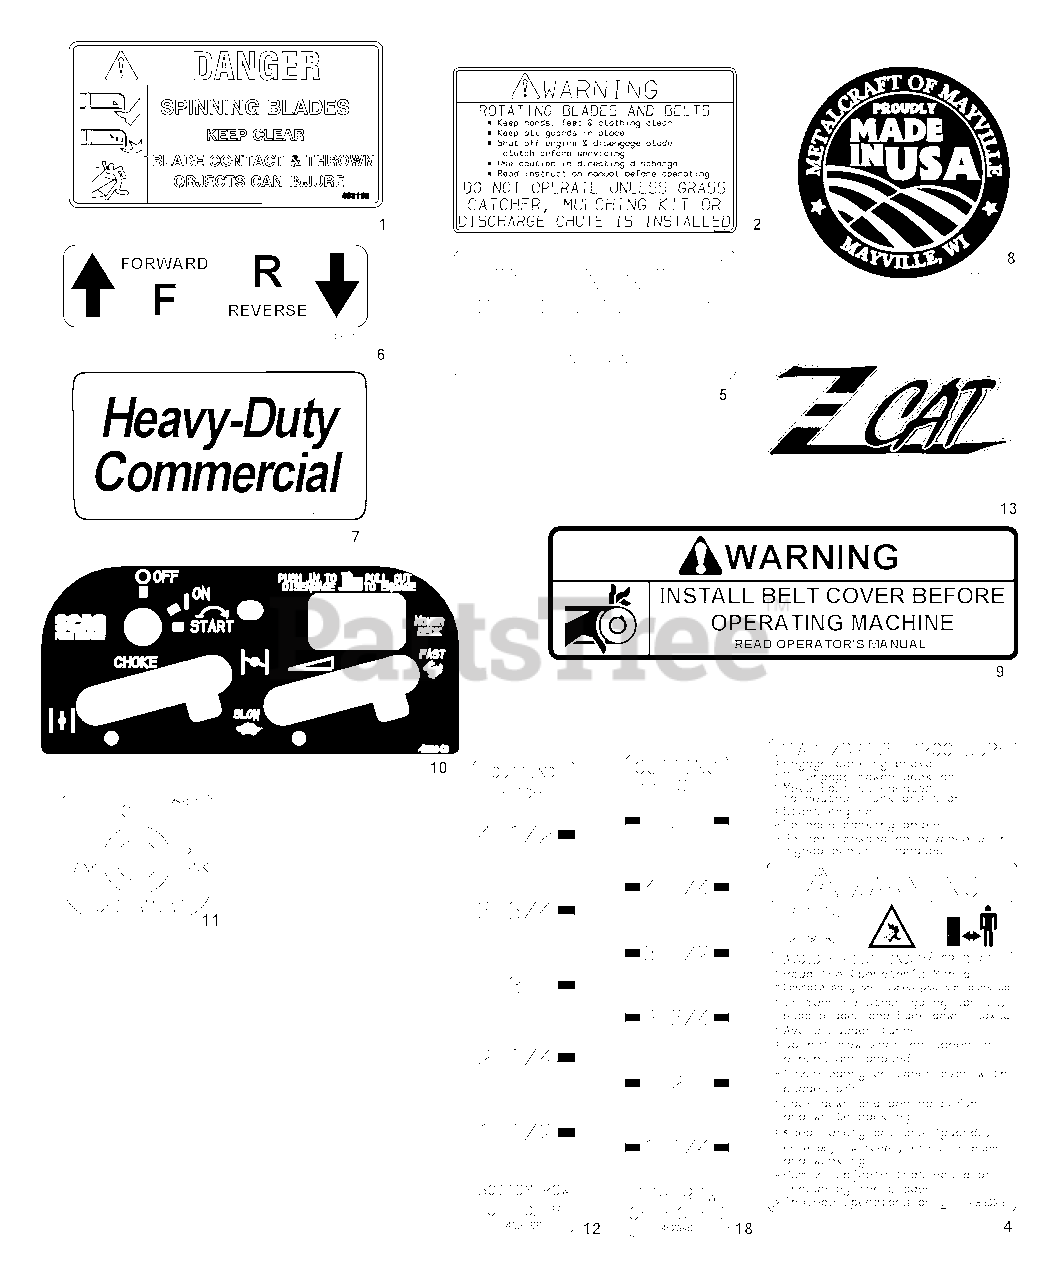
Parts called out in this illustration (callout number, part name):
1	Decal, Danger-Spinning Blades
2	Decal, Warning-Rotating Blades
4	Decal, Fuel Tank Start/Drive
5	Decal, Patents
6	Decal, Traction Control
7	Decal, Heavy Duty Commercial
8	Decal, Metalcraft - Made in USA
9	Decal, Belt Cover
10	Decal, Instrument Panel
11	Decal, Fuel Shutoff
12	Decal, Cutting Height Bottom Row of Holes
13	Decal, Front SZC
18	Decal, Cutting Height Top Row of Holes
